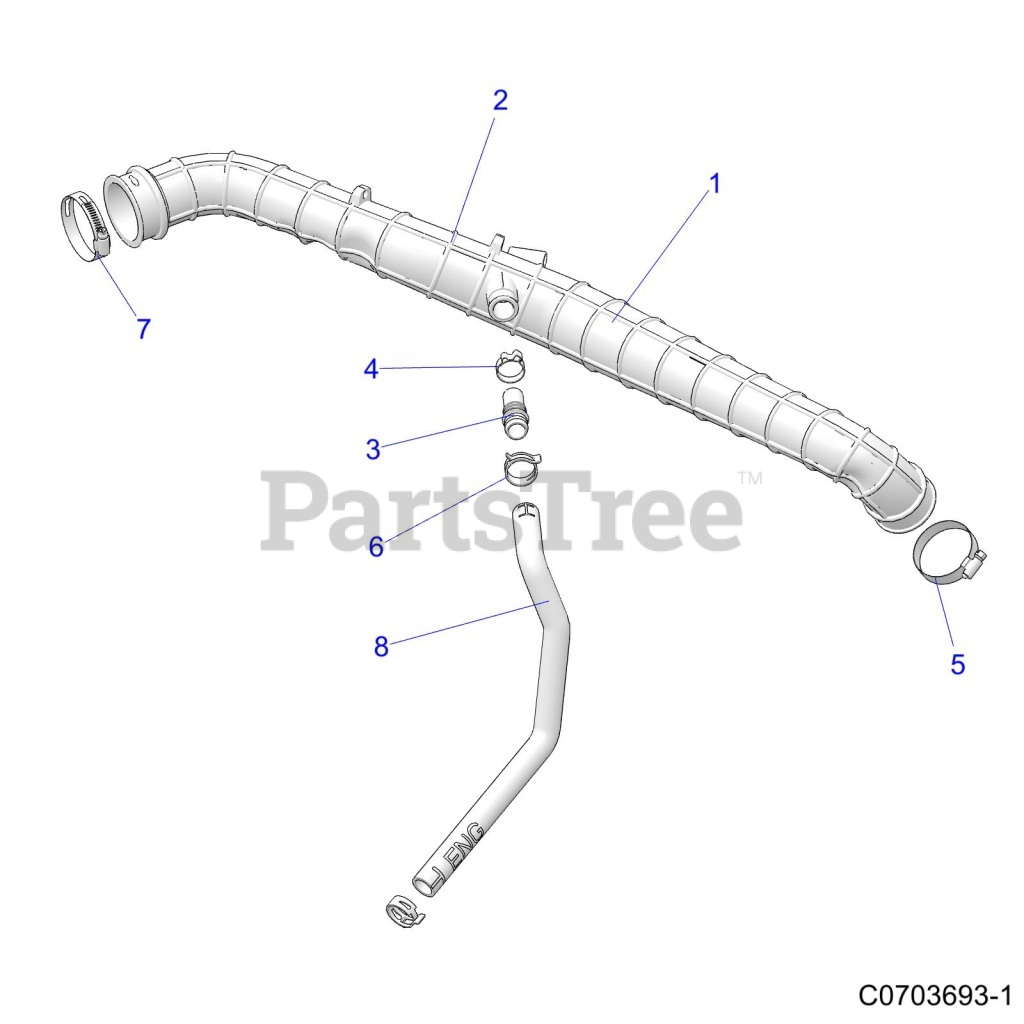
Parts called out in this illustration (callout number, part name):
1	ASM-INTAKE,POST-FILTER
2	HOSE-INTAKE,POST-FILTER
3	FITTING-3/4 DOUBLE BARB
4	CLAMP-HOSE
5	CLAMP, HOSE, S.S.(10)
6	SPRINGBAND-CLAMP 27/12,GREEN
7	CLAMP-HOSE SLOTTED,60-80 DIA
8	HOSE-VENT,ENGINE
